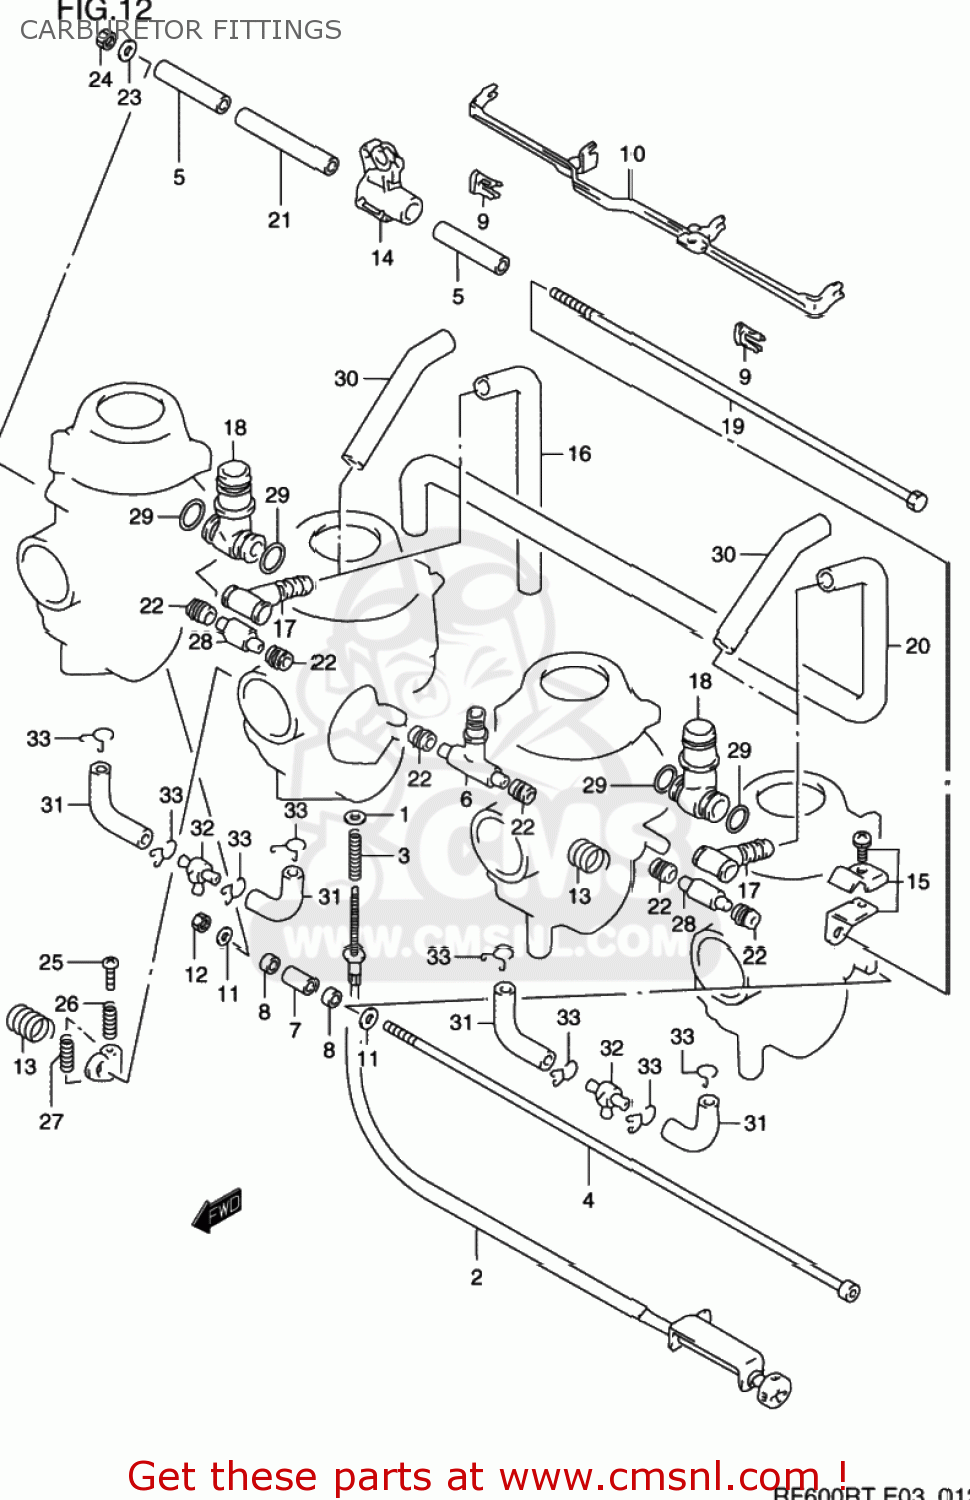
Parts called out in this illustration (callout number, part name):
1	WASHER
2	SCREW,ADJUST
3	SPRING
4	BOLT
5	RING
6	NIPPLE
7	RING
8	RING
9	HOLDER
10	LEVER,STARTER
11	WASHER
12	NUT
13	SPRING
14	LEVER
15	BRACKET ASSY
16	HOSE
17	3 WAY
18	NIPPLE
19	BOLT
20	HOSE
21	RING
22	SEAL
23	WASHER
24	NUT
25	SCREW
26	SPRING
27	SPRING,THROTTLE SCREW
28	PIPE
29	O-RING
30	HOSE
31	HOSE
32	NIPPLE
33	CLIP
